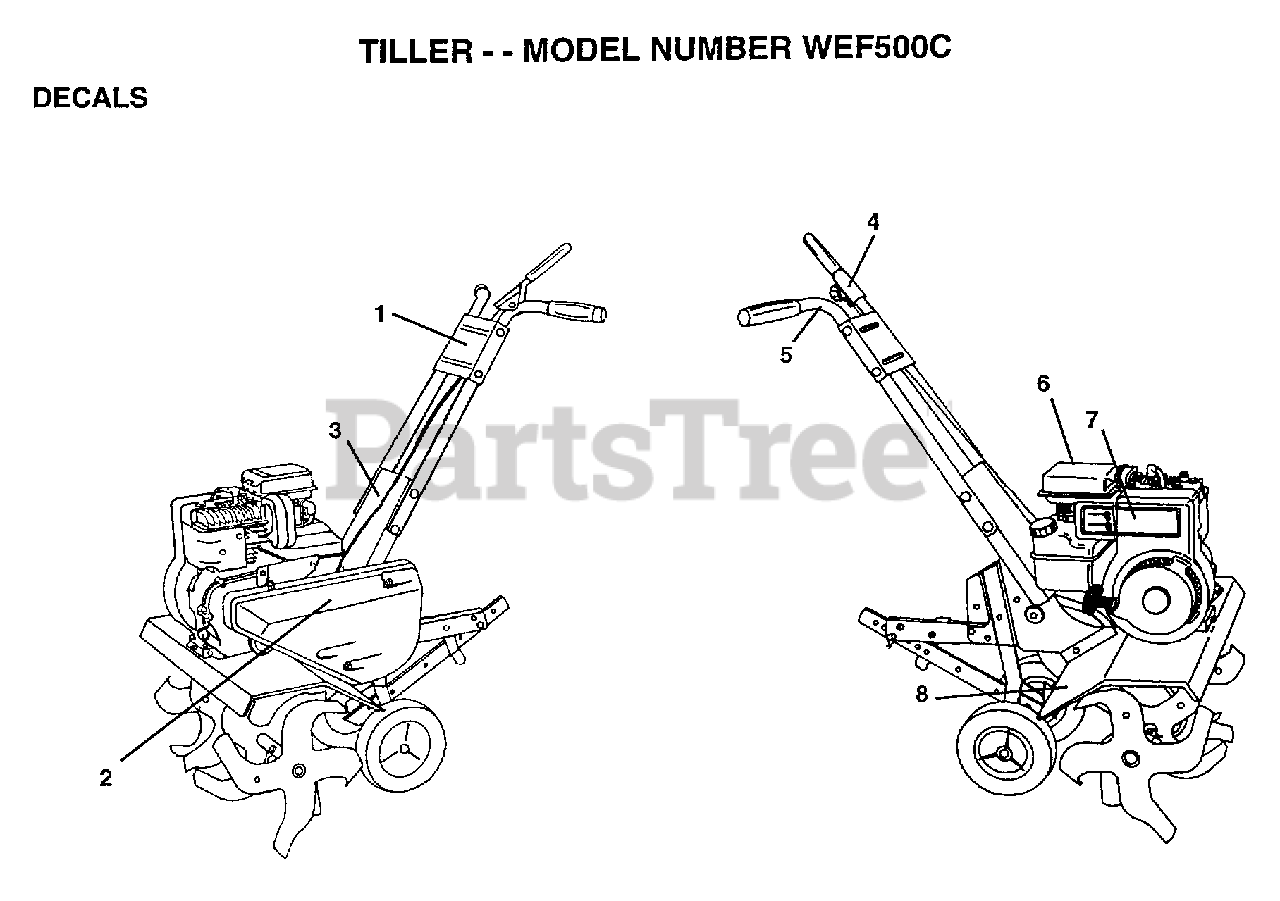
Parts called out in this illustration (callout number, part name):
2	DECAL.WEF500B
3	DECAL.WEF500B
4	DECAL TI
5	DECAL TI
6	DECAL TI
7	DECAL, BRIGGS & STRATTON
